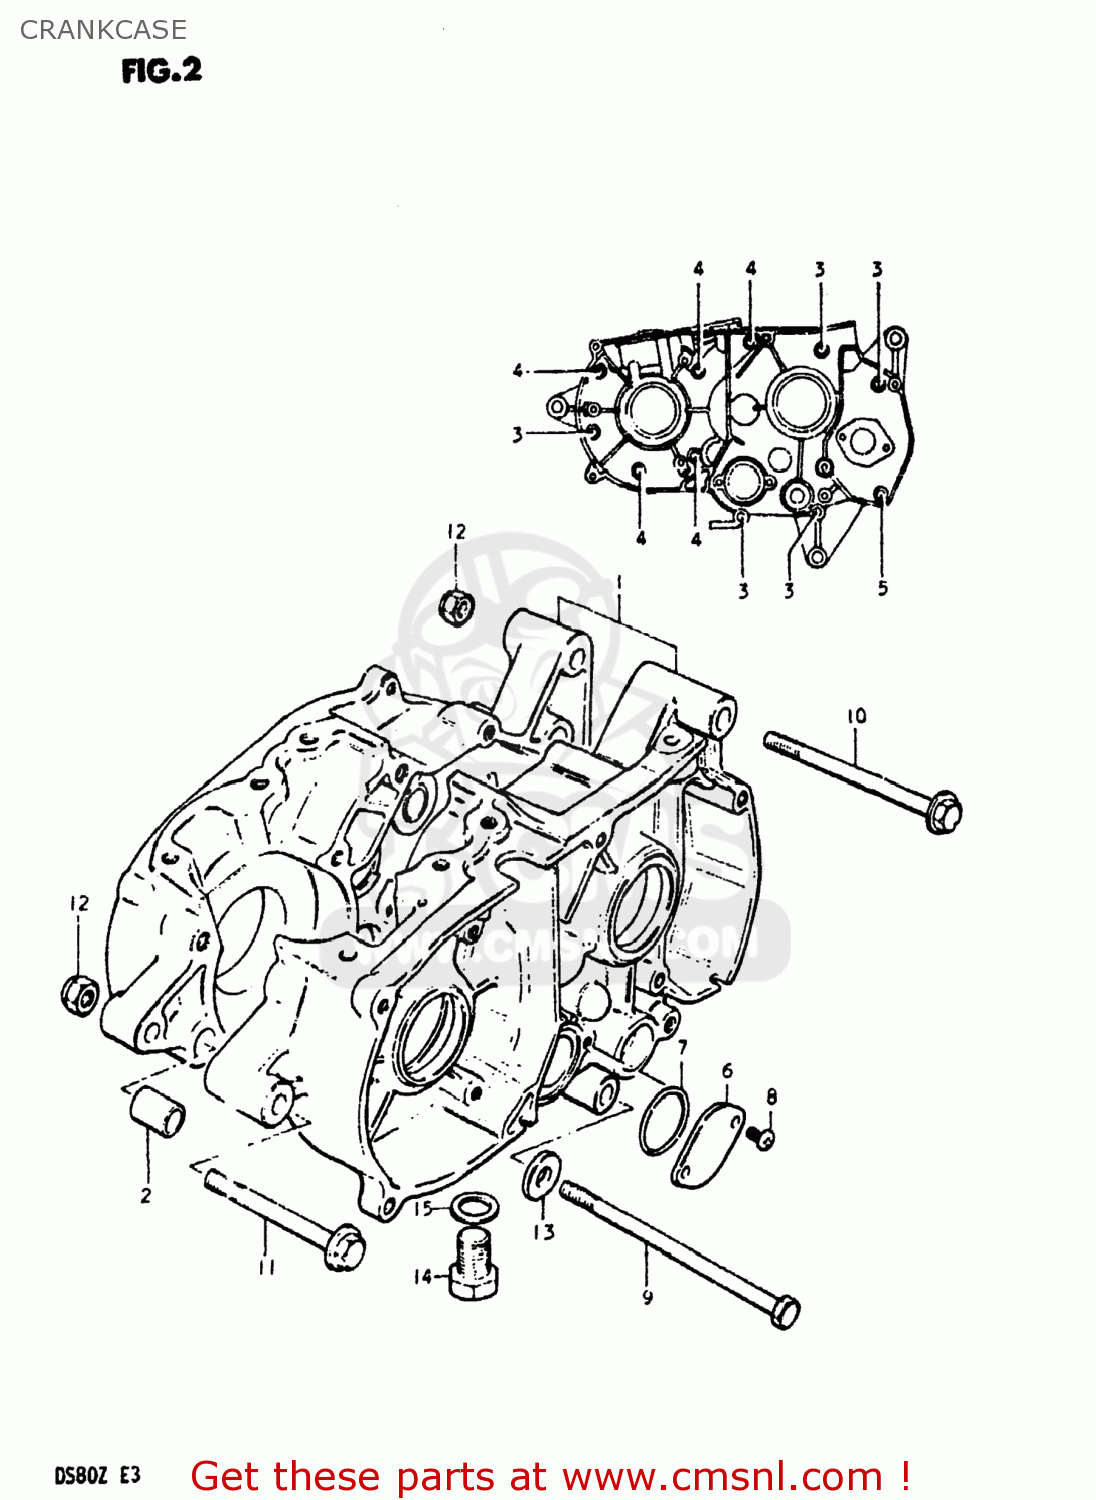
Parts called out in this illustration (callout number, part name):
1	CRANKCASE SET
2	PIN
3	SCREW (6X45)
4	SCREW (6X35)
5	SCREW
6	CAP,GEAR SHIFT CAM PIVOT
7	O-RING (D:2.4 ID:26.2)
8	SCREW
9	BOLT
10	BOLT
11	BOLT 8X75
12	NUT
13	WASHER
14	BOLT 10X20
15	GASKET(10X14X3.6) (NAS)
